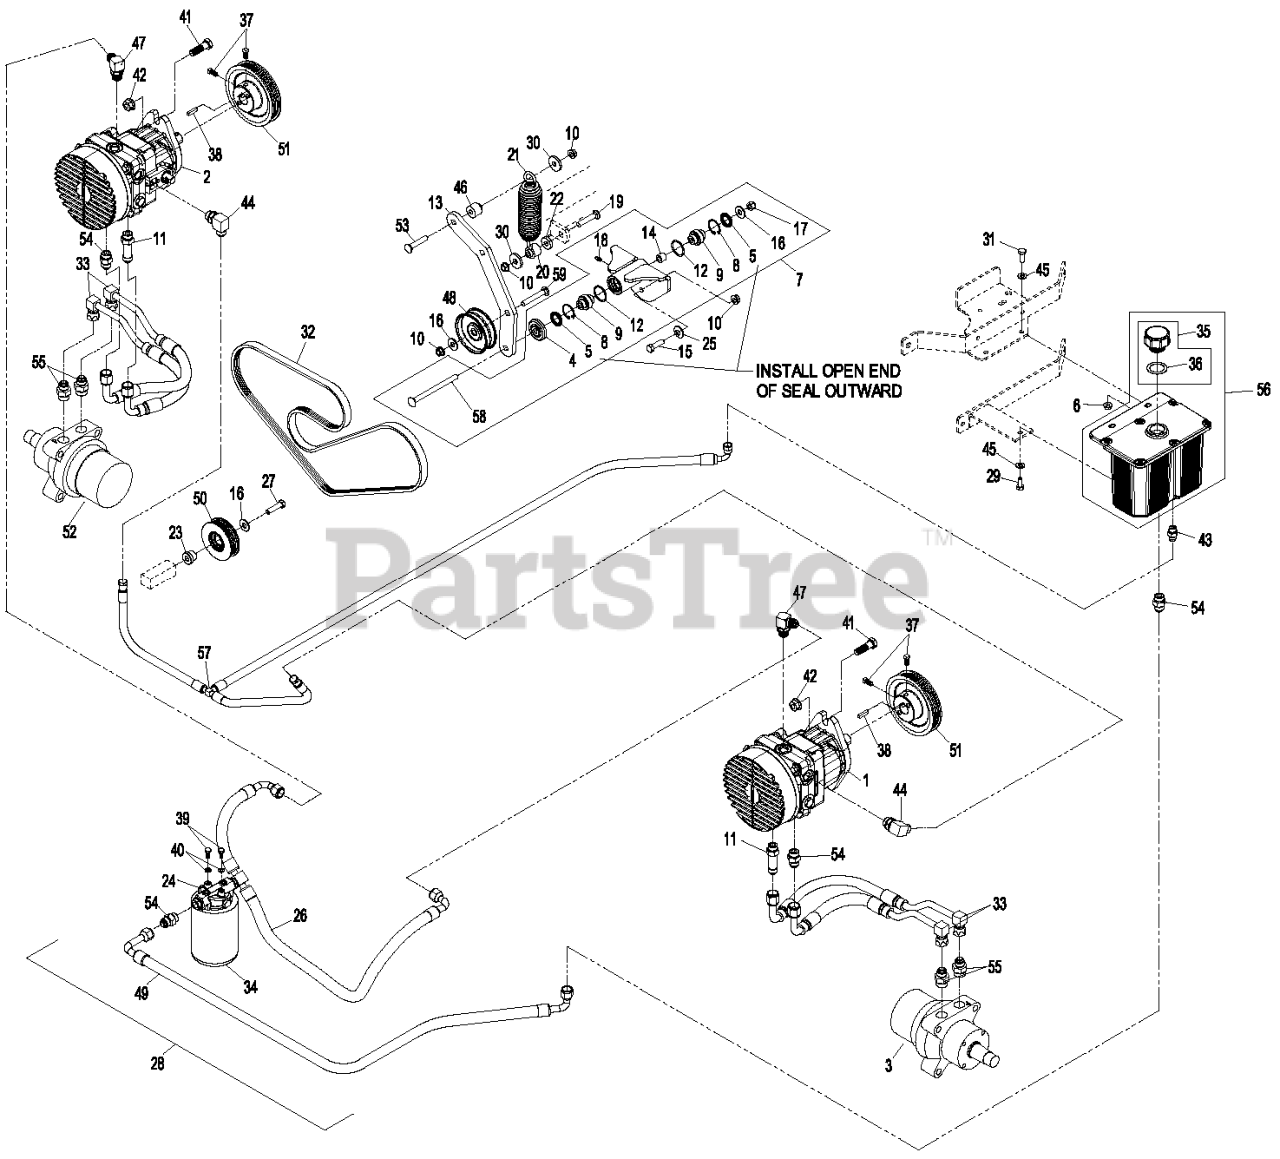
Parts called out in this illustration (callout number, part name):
1	PUMP, LH
2	PUMP, RH
3	HYD MOTOR ASM (CCW)
4	GUARD-TOP
5	SEAL-LIP, SINGLE
7	KIT,XS PUMP IDLER
8	RING-SNAP
9	BEARING-SPHERICAL
10	NUT-HHF, WHIZ
11	ADAPTER-STR, LONG
13	ARM, XS HYDRO TIGHTENER
15	SCREW-HH
16	WASHER-FLAT
17	NUT-LOCK, NI
18	FITTING-GREASE
19	BOLT-CARR, SHORT NECK
20	SPACER-SPRING, FAN PUMP
22	SPACER-BRACKET, GUIDE
23	SPACER,LOWER FRAME IDLER
24	HEAD-FILTER
25	WASHER-BELLEVILLE
26	ASM, HOSE-PUMP INLET
27	SCREW-HH
28	Asm, Charge Hose
29	SCREW-HH
31	SCREW-HH
32	BELT, 5K 68.8
33	HYD HOSE ASM
34	FILTER,XP HYD 25 MICRON
35	KIT,HYD RES CAP W/GASKET
36	GASKET-CAP
37	SCREW-SET
39	SCREW-HH
40	WASHER-LOCK
41	SCREW-HH
42	NUT-HHF
43	FITTING-STRAIGHT
44	FITTING-ELBOW, 90 DEG
45	WASHER-PLAIN
47	FITTING-90 DEG
48	IDLER,PUMP
49	ASM, HOSE-FILTER INLET
50	ASM,LOWER FRAME IDLER
51	SHEAVE,5K 5.0" PD POLY-V
52	HYD MOTOR ASM (CW)
53	SCREW-CARR
54	FITTING-STRAIGHT
55	FITTING-STRAIGHT
56	HYDRAULIC TANK ASM
57	ASM,CASE DRAIN HOSE
58	BOLT CARR 3/8-16X5
59	SCREW-CARR
